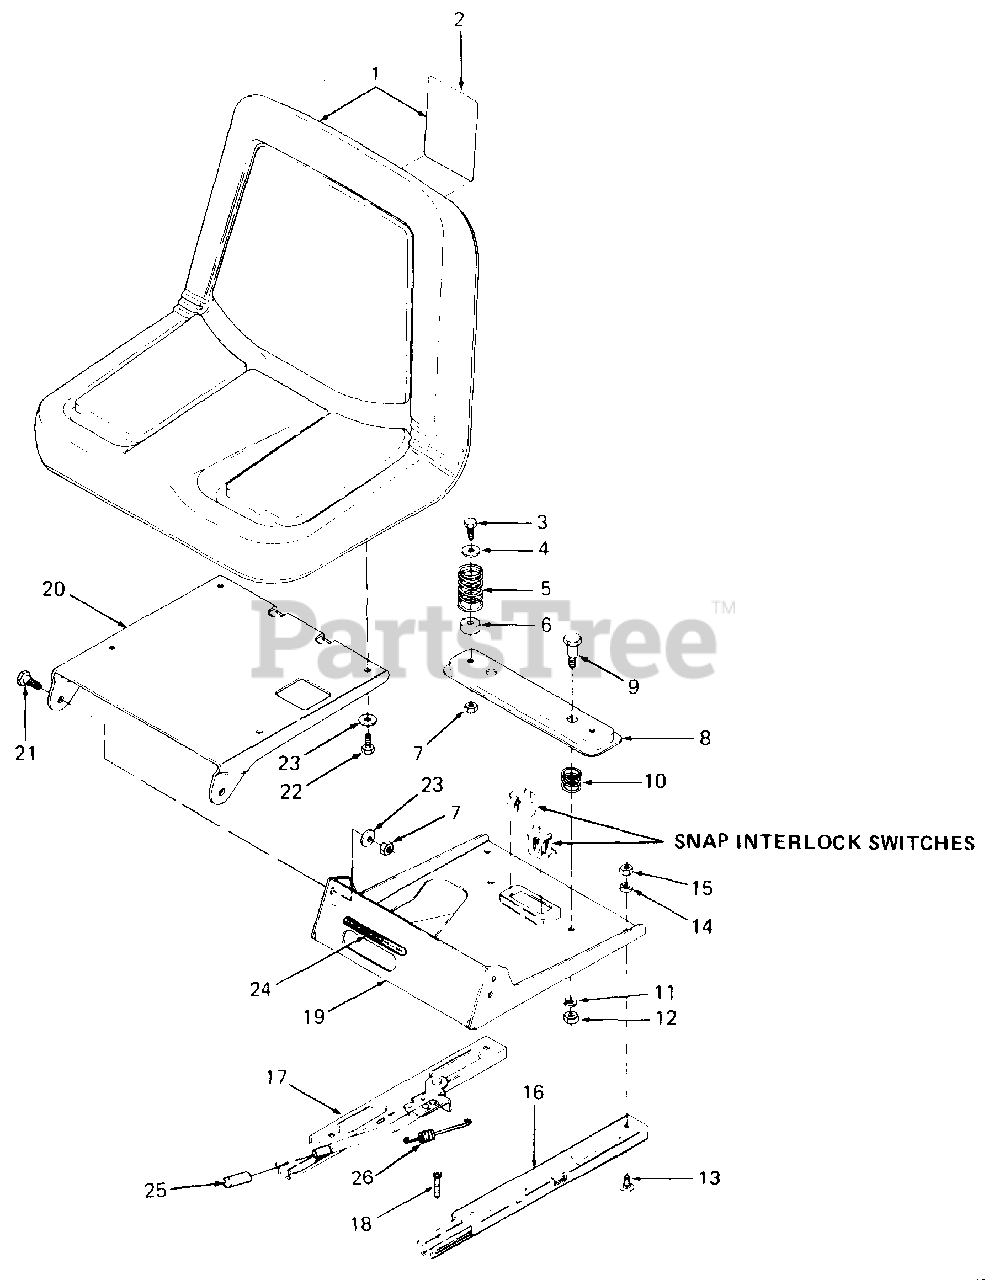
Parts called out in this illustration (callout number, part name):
1	Seat w/Graphic
2	Graphic, Caution
3	Screw, Hex Cap, 5/16-18 x .88 Lg GR5
4	Washer, Flat, .344 x .875 x .06 Thk
5	Spring, Comp, 1.28 OD x 2.18 Lg
6	Bushing, .930 OD x .50 Lg
7	Nut, Hex Center Lock, 5/16-18 GR5
10	Spring, Comp, 1.00 OD x .86 Lg
11	Washer, Lock, 3/8
12	Nut, Hex, 3/8-16 GR5
13	Bolt, Sht Nk Carriage, 5/16-18 x .62 Lg
14	Washer, Lock, 5/16
15	Nut, Hex, 5/16-18 GR5
16	Slide, Seat - LH
17	Adjuster, Manual Seat - RH
18	Screw, Socket Hd Cap, 5/16-18 x 1.00 Lg
22	Screw, Hex Cap, 5/16-18 x .75 Lg GR5
23	Washer, Bell, .345 x .88 x .060 Thk
24	Label, Seat Adjustment
25	Cover, Handle
